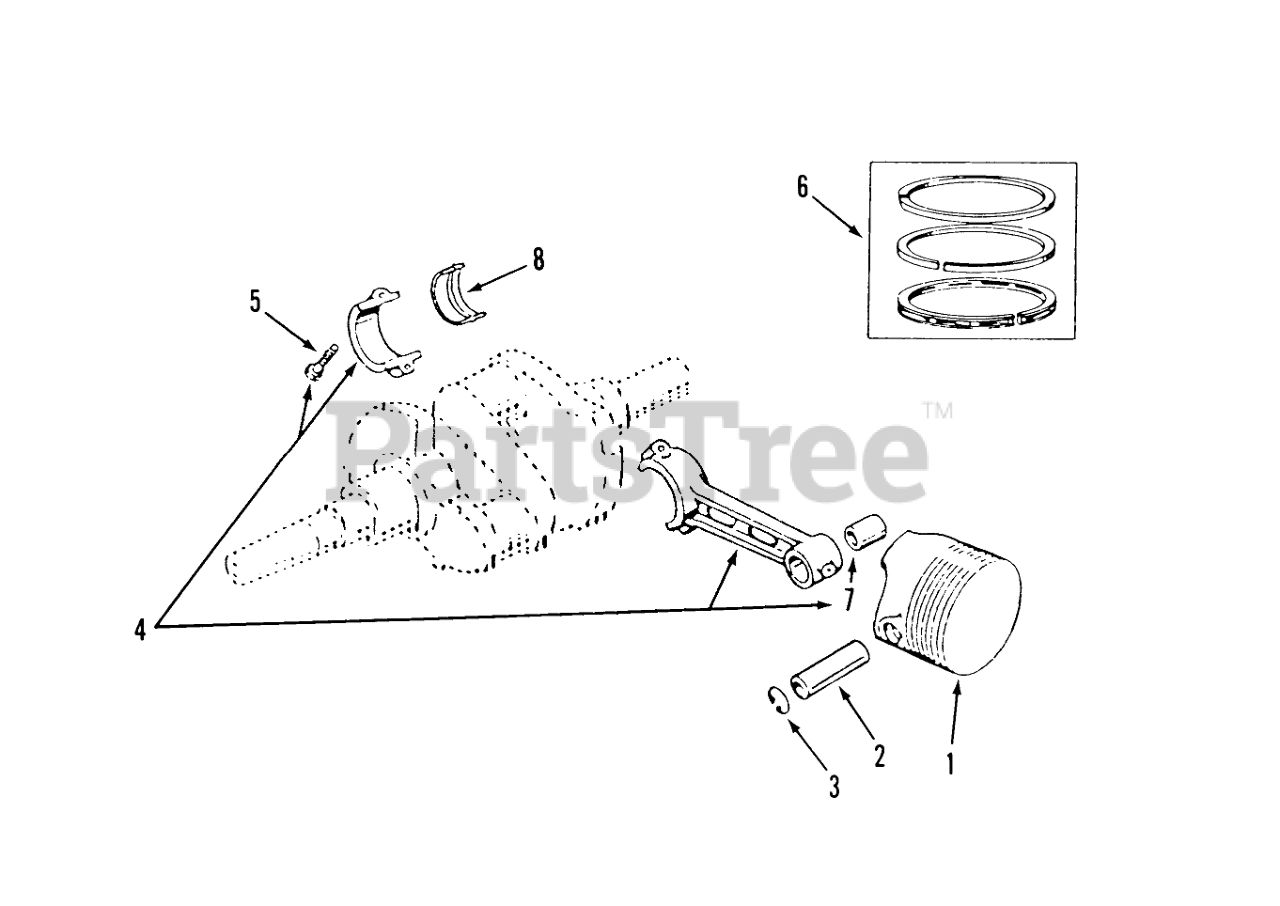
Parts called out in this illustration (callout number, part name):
1	Piston & Pin (Incl. Pin & Retaining Ring)
2	PIN-PISTON
3	RETAINING RING
4	Rod-Connecting (Incl. Bolts)
5	BOLT-PLACE
6	Set-Piston Ring
7	BUSHING-PISTON PIN
8	Bearing-Connecting Rod, Half
